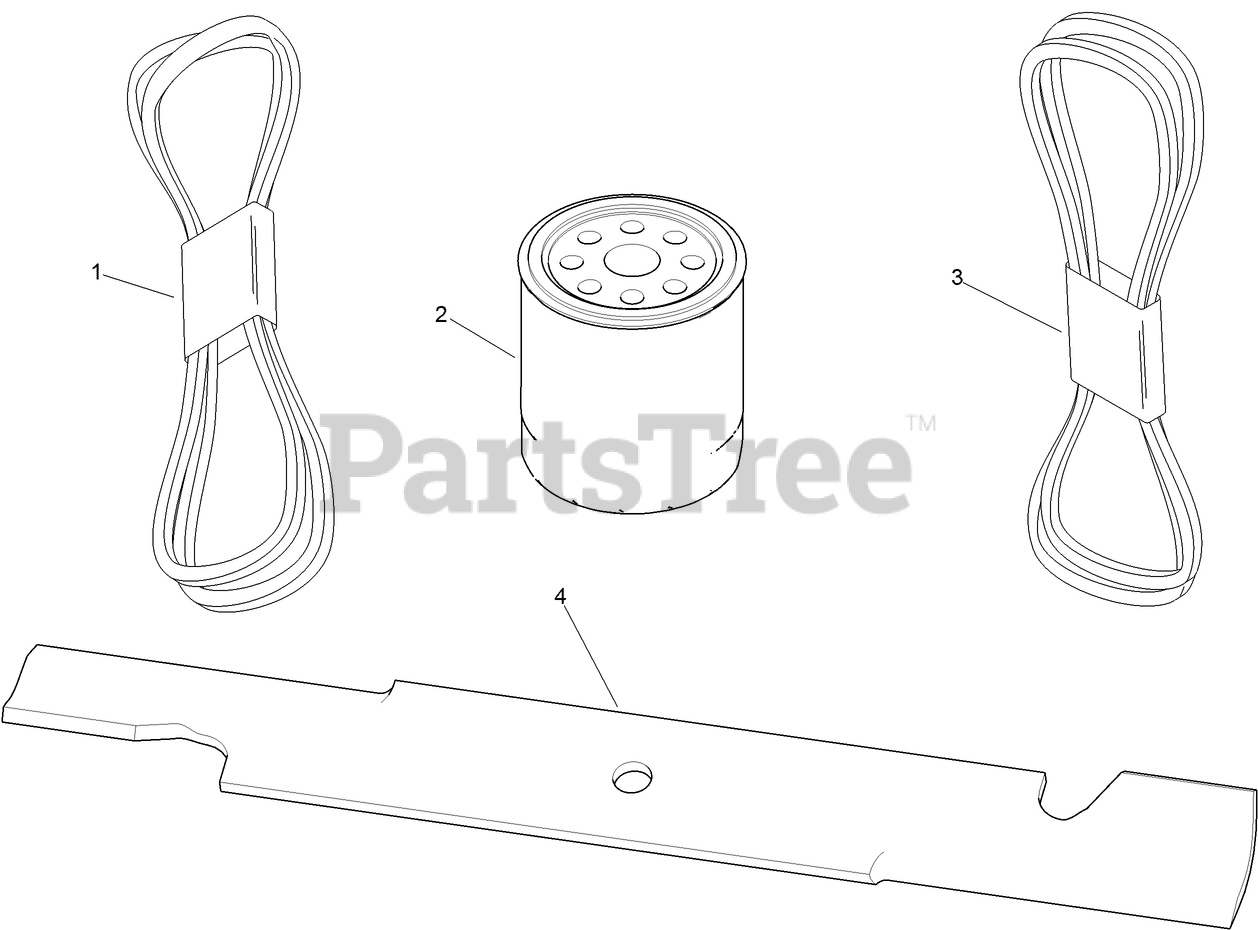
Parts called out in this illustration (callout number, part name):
1	BELT-V, LOWER PTO
2	ELEMENT-FILTER, 25 MICRON
3	BELT-V
4	BLADE-HI FLOW
